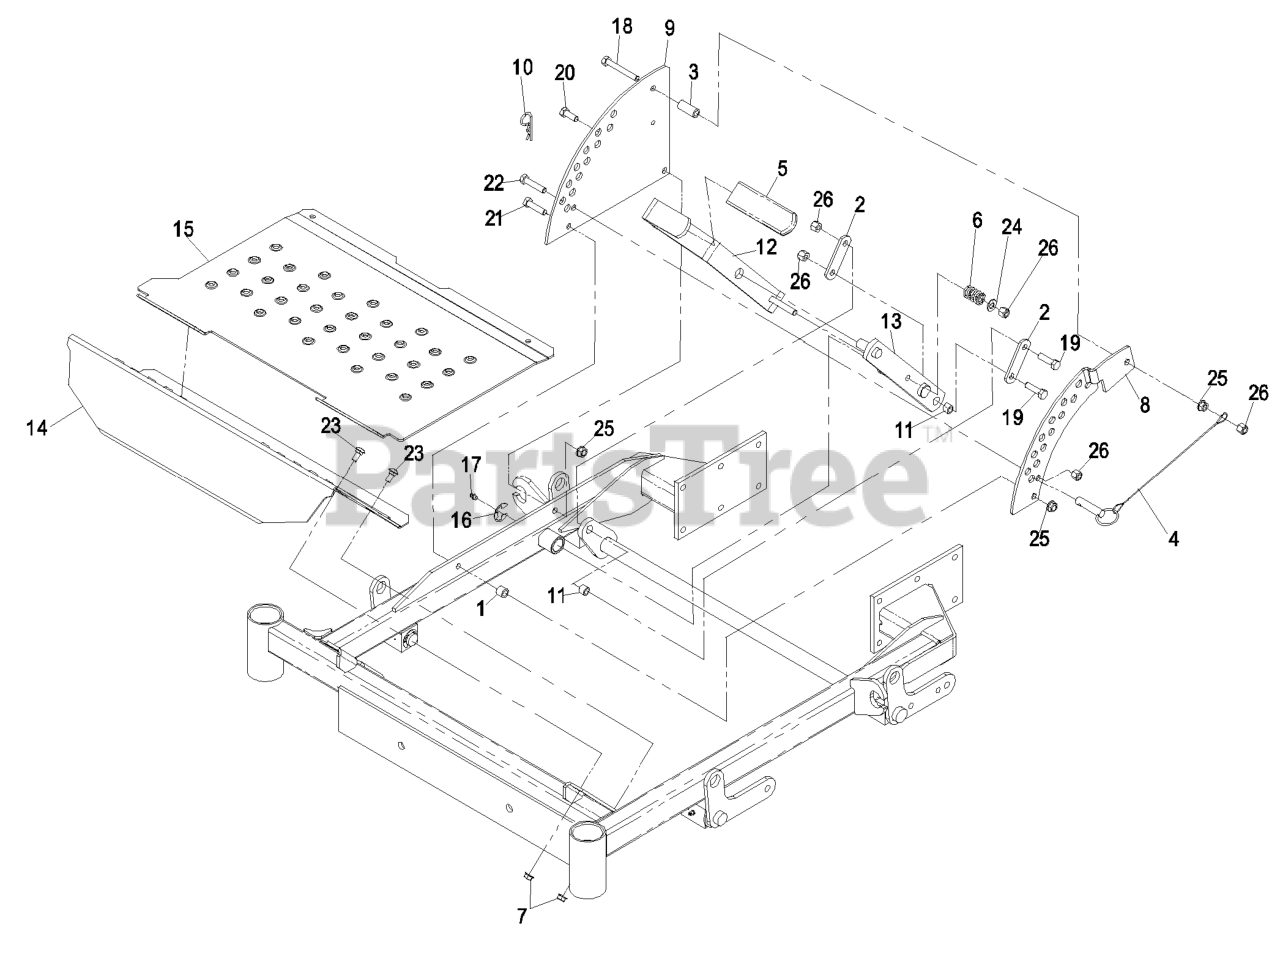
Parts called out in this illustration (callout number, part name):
1	BUSHING-LEVER, LIFT
2	ARM-LIFT, DECK
3	BUSHING-LEVER, LIFT
4	PIN-HITCH (W/LANYARD)
5	GRIP-LEVER, LIFT
6	SPRING-COMPRESSION
8	PLATE-LIFT, DECK W/DECAL
9	PLATE-LIFT, DECK
10	PIN-COTTER
11	BUSHING
12	ASM, LIFT LEVER / GRIP
13	WLD, DECK LIFT ARM-LHP
15	ASM,FLOORPAN
16	RING-RETAINING, EXT
17	FITTING-GREASE
18	SCREW-HH
19	SCREW-HH
20	SCREW-HH
21	SCREW-HH
22	SCREW-HH
23	BOLT-CARR
24	WASHER-FLAT
25	NUT-HHF, WHIZ
26	NUT-LOCK, NI
